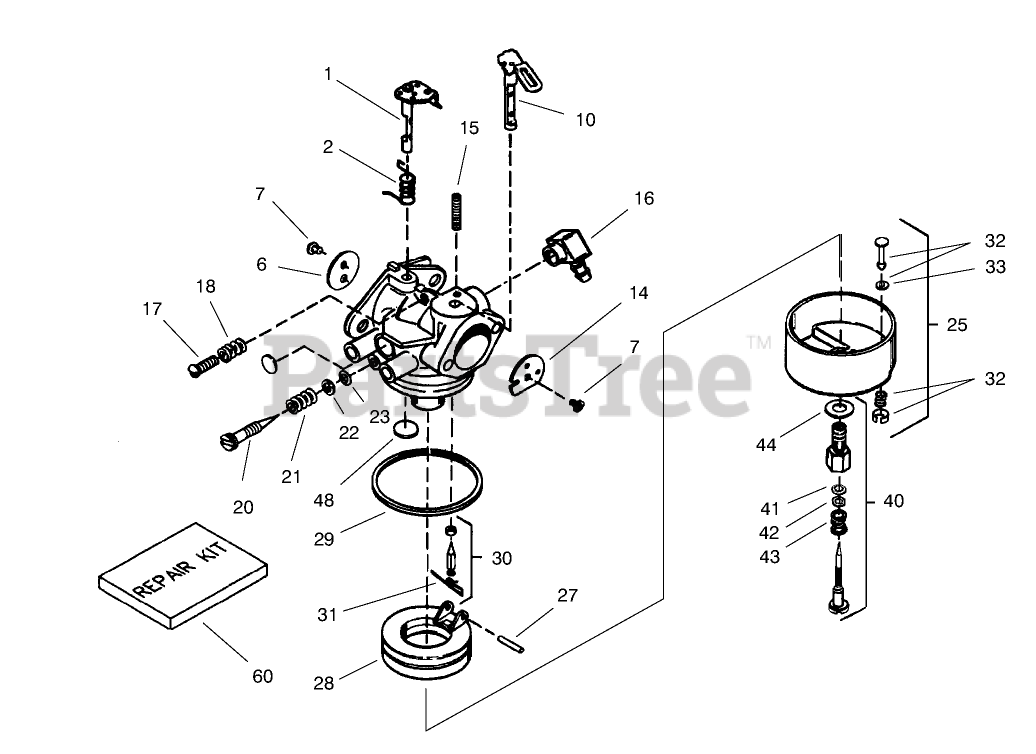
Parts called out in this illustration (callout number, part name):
1	Throttle-Shaft Lever Asm
2	Spring-Return, Throttle
6	Shutter-Throttle
7	Screw-Shutter
10	Choke Shaft Lever ASM
14	Choke Shutter
15	Spring-Positioning, Choke
16	Fitting-Fuel
17	Screw-Throttle Crack Screw / Idle Speed
18	Spring-Tension
20	Screw-Idle Mix
21	Spring-Tension
22	Washer
23	ORing
25	Float-Asm (Incl. Ref. # 32 33)
27	Shaft-Float
28	Float
29	O Ring-Bowl, Float
30	Inlet Needle, Seat Clip Assy. (Incl. No. 13)
31	Clip-Spring
32	Bowl Drain ASM
33	Gasket-Plunger, Drain
40	Adjustment Screw Assy.,Main (Incl. Ref. #5A,21,23 30)
41	ORing
42	Washer
43	Spring
44	Washer-Bowl Nut
47	Plug-Welch, Idle Mixture Well
48	Plug-Welch, Atmospheric Vent
60	Kit-Repair
